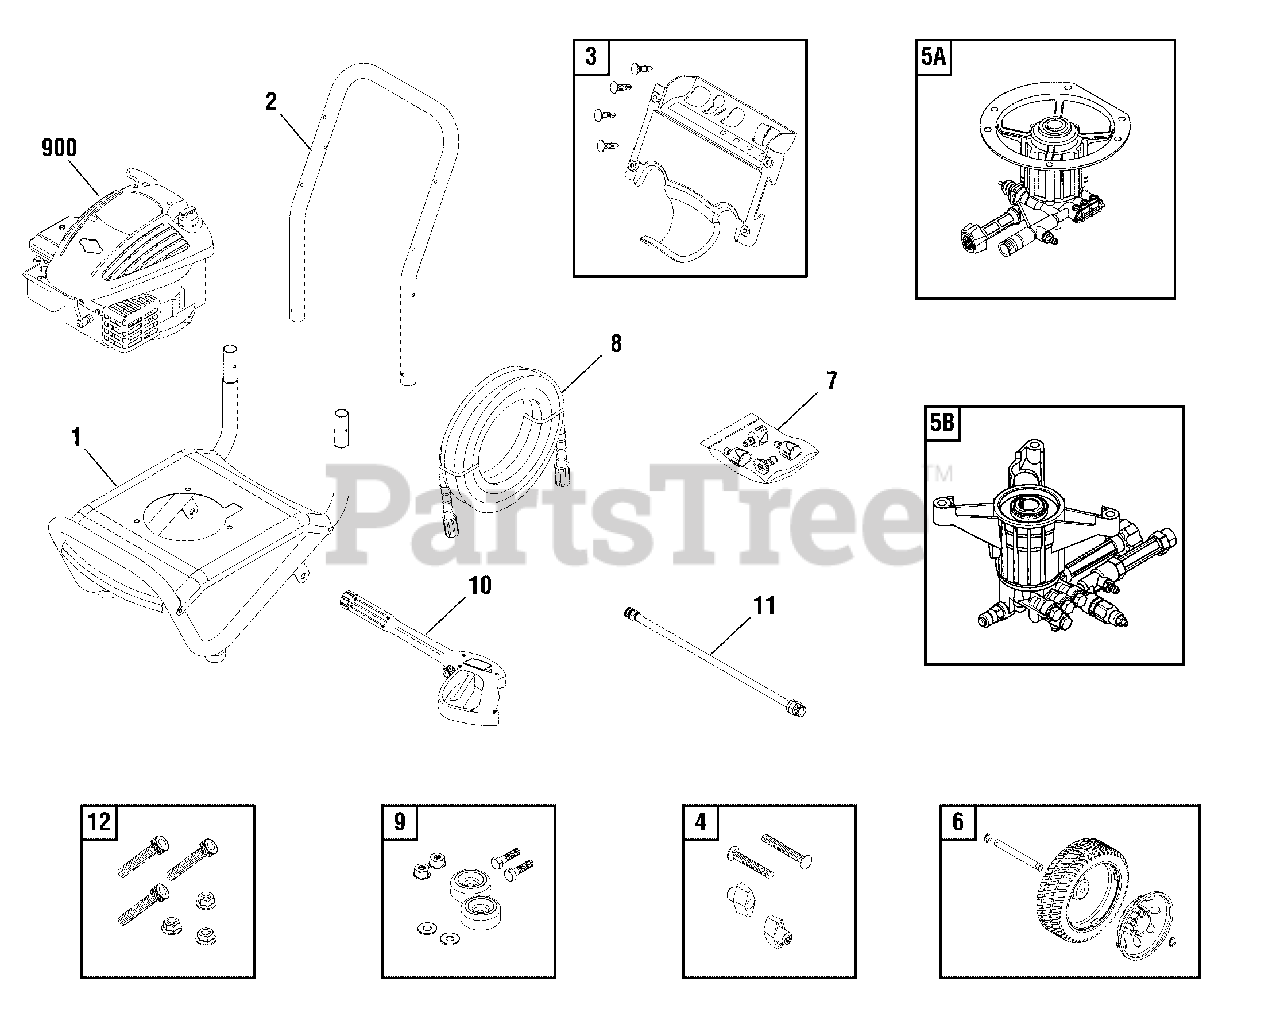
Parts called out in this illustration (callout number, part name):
1	BASE, With Mounts
2	HANDLE
3	BILLBOARD
4	KIT, Hardware, Handle
5A	PUMP
7	KIT, Spray Tips
9	KIT, Vibration Mount
10	GUN
11	EXTENSION, QC
12	KIT, Hardware, Pump Mounting
900	* ENGINE
